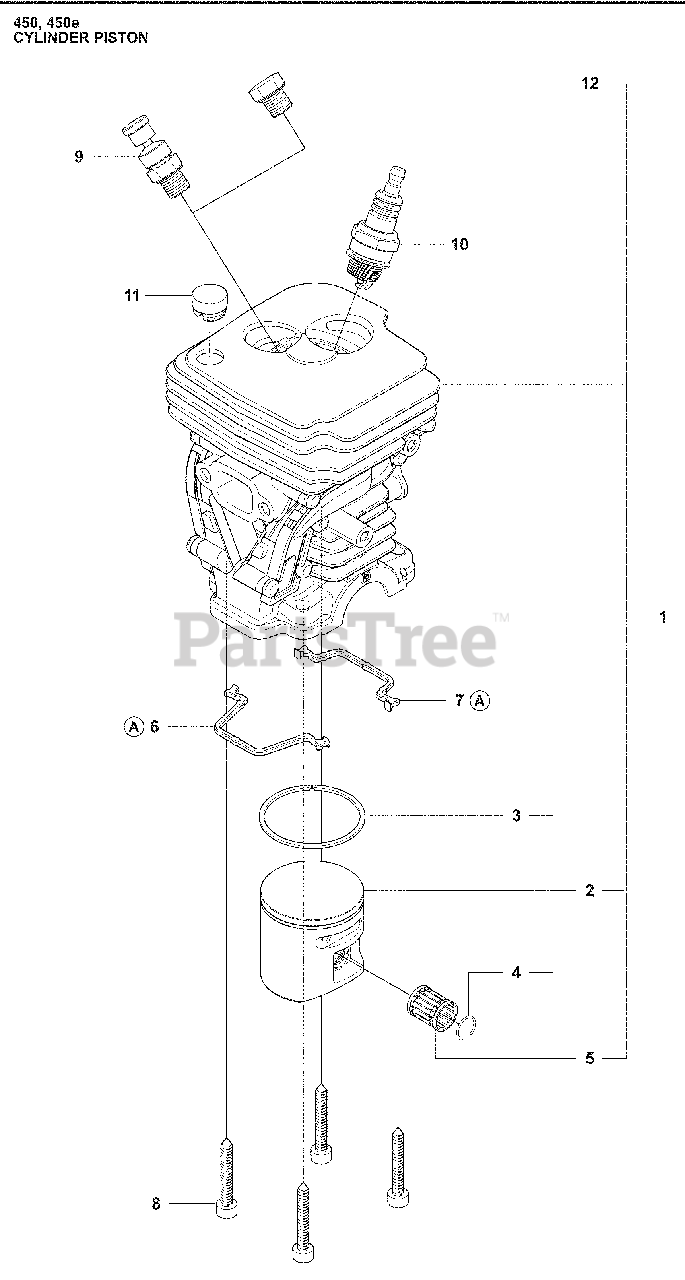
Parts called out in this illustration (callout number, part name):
2	Piston Assembly
3	Piston Ring
4	Circlip, 10mm
5	Support Bushing
9	Decompression Valve
10	Solid Spark Plug, BPMR7A
12	Cylinder Plug
